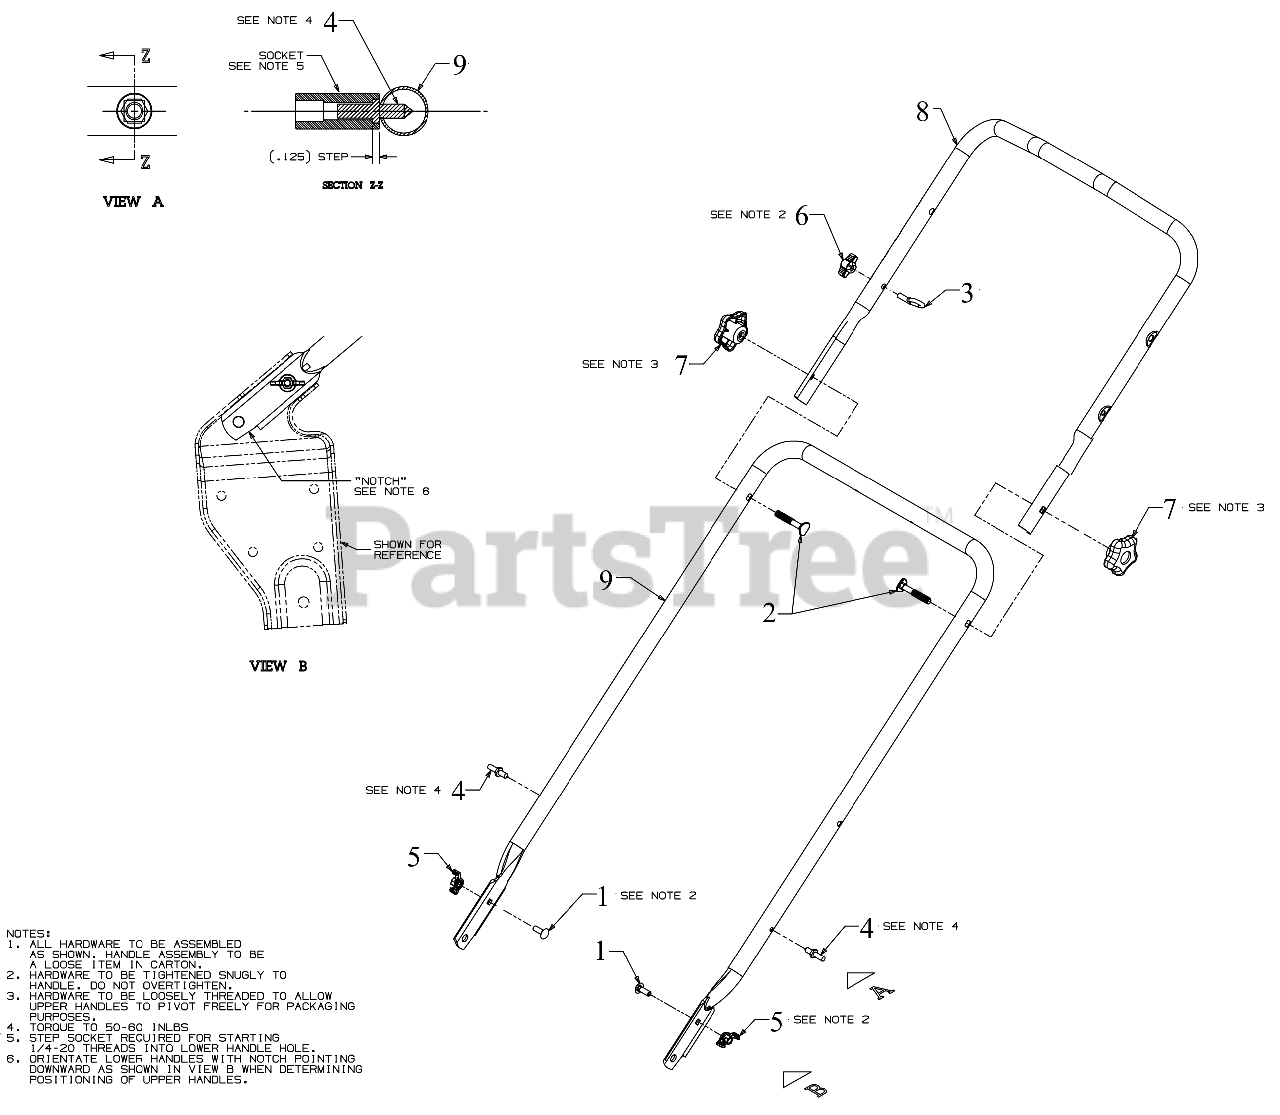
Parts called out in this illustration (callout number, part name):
1	SCREW 1/4-20 x .75 GR5
2	SCREW .312-18X2.0
3	EYEBOLT 1/4-20
4	BELT KEEPER PIN 1/4-20
6	HANDLE KNOB
7	STAR KNOB 5/16-18
